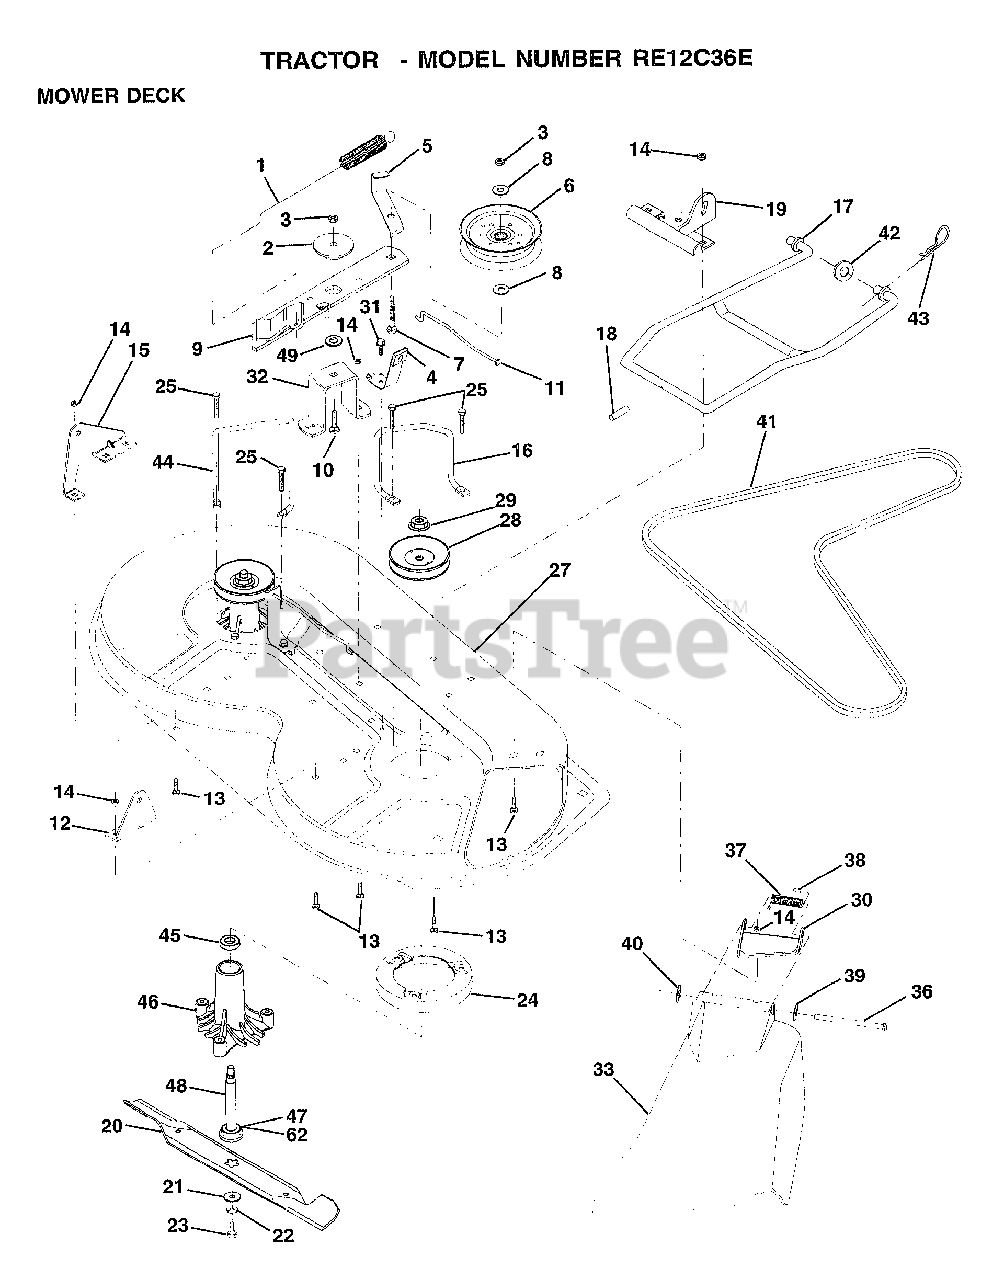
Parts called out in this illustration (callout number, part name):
1	SPRING CLUTCH MWR
2	SPACER.RETAINER.MOWER
4	BRAKE ASM
5	IDLER BELT GUIDE
6	PULLEY IDLER
7	BOLT
8	WASHER
10	BOLT.3/8-14X1.25
11	BRAKE ROD
12	"BRKT,LIFT REAR"
13	BOLT
15	"BRKT,LIFT REAR LH"
16	"KEEPER-BELT,RH"
17	MOWER LINK STAB
18	"PIN,GROOVE"
19	"BRKT,LINK STABILI"
20	"BLADE.36"" HIPERF"
21	WASHER.HARD.BLADE
23	BLADE BOLT
24	STRIPPER RND MWR
25	"SCREW-THD ROLL,WA"
27	"HOUSING-MOWER,36"""
28	PULLEY.MAND.36/46
31	SCREW LT
32	"SUPT,IDLER ARM"
33	SHIELD, DEFLECTOR
36	HINGE ROD
37	SPRING TORSION
38	CAP-SLEEVE LT
39	WASHER
40	NUT PUSH M
41	V-BELT.PRIM.78.5.
43	RETAINER SPRING
44	KEEPER BELT LH
45	BEARING
46	HSG ASM MANDREL
47	BEARING.BALL
49	HARDENED WASHER
62	WASHER.FELT.
